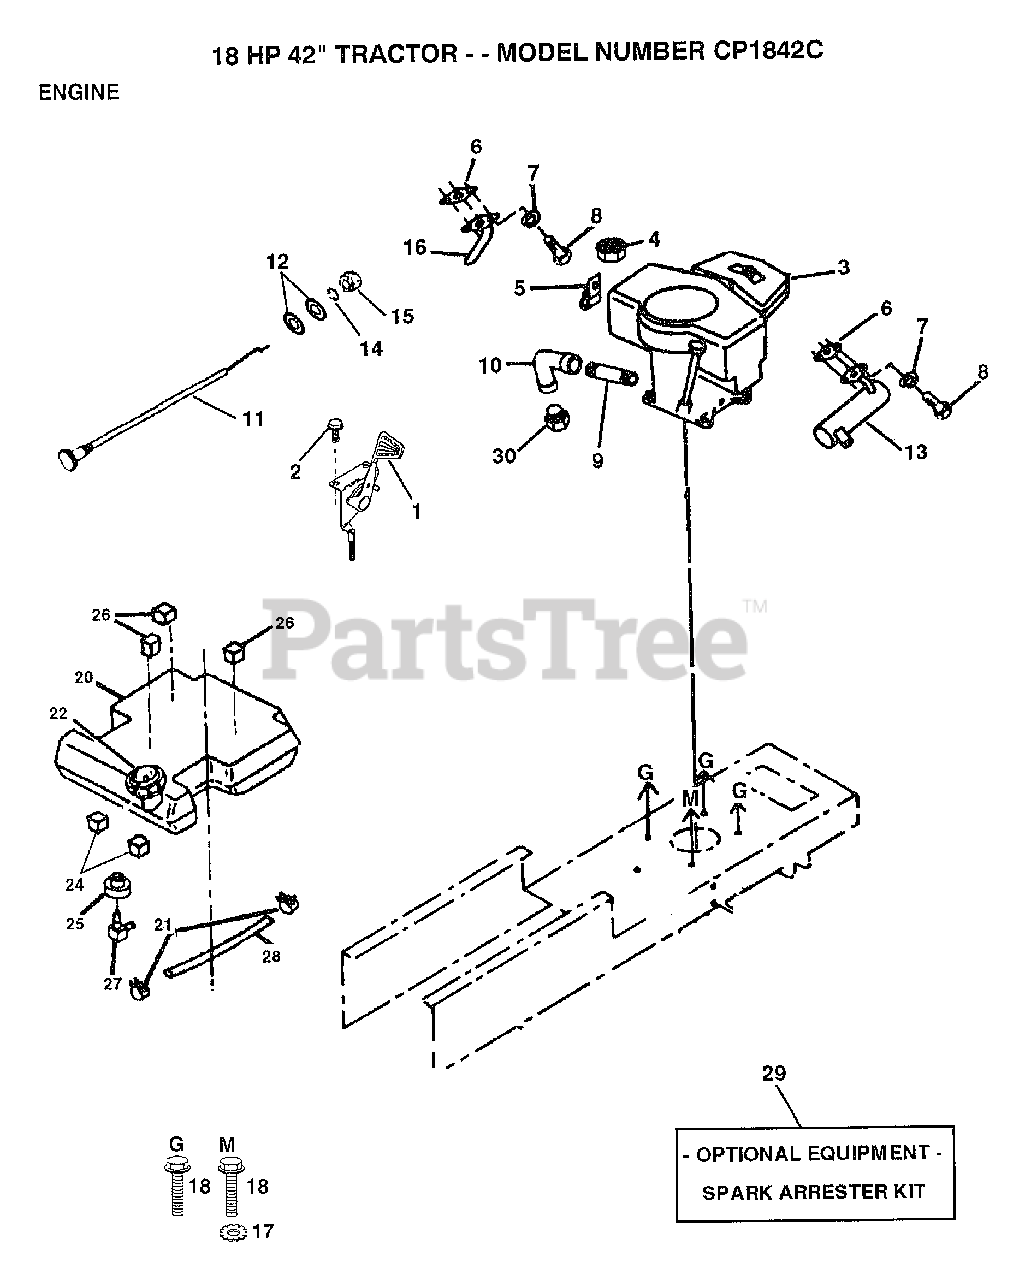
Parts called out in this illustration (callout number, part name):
2	SCREW LT
4	NUT
5	CLIP T
7	LOCKWASHER
9	PIPE NIPPLE LT
10	ELBOW
11	CHOKE CONTROL
12	WASHER
14	LOCKWASHER
16	EXHAUST TUBE T
17	LOCKWASHER
18	SCREW LT
21	HOSE CLAMP
24	PAD IDLER TI
25	BUSHING OUTLET T
26	PAD-SPACER LT
27	FUEL TANK STEM GT
29	SPARK ARREST KIT
